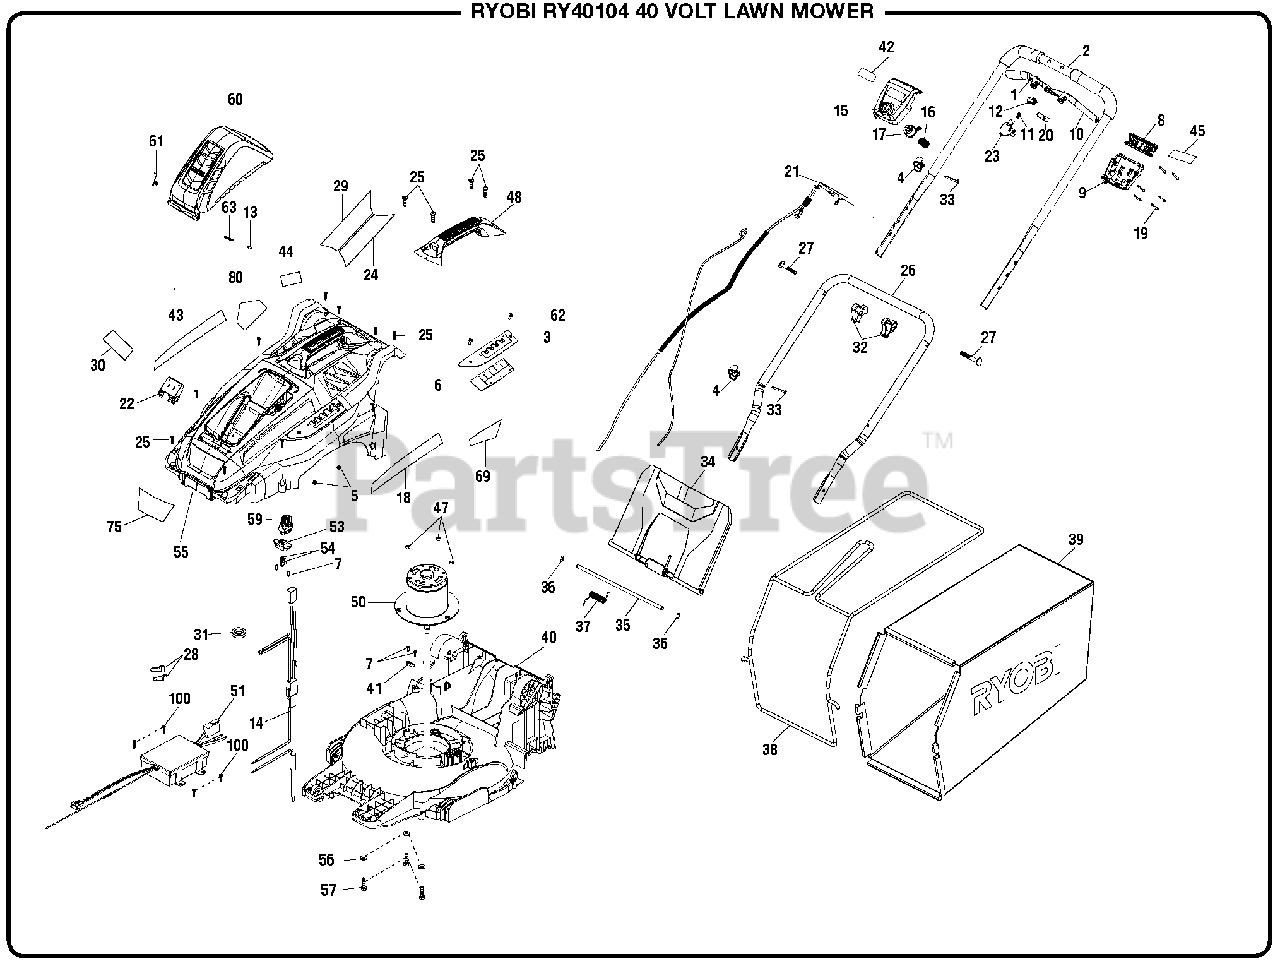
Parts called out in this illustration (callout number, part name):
1	Trigger Handle (Right Power Lever)
2	Upper Handle Assembly
3	Height Adjustment Plate
4	Cord Clamp
5	Lock Nut (M5)
6	Dust Gasket
7	Screw (M4 x 16, T20 Torx Hd.)
8	Lower Cover (Stain Handle)
9	Lower Cover (Trigger Housing)
10	Trigger Handle (Left Power Lever)
11	Compression Spring
13	Battery Door Axle
14	Terminal Block w/Leads
15	Upper Cover (Control Assembly)
16	Compression Spring
17	Start Button
18	Lithium Label (Left)
19	Screw (M4 x 30 mm, T15 Torx Pan Hd.)
21	Starter Cable (Long)
22	Battery Holder Assembly
23	Switch Holder
24	Warning Icon Label (Right)
25	Screw (M3.5 x 20 mm, T20 Torx Pan Hd.)
26	Lower Handle
27	Screw (M8 x 57 mm)
28	Wire Connector
29	Warning Icon Label (Left)
30	Start Key Label (Eng)
31	Ferrite Induct Ring
33	Screw (M3 x 20 mm, Pan Hd.)
34	Rear Discharge Door
35	Rear Door Axle
36	Retaining Ring (E)
37	Torsion Spring (Rear Door)
38	Bag Frame
41	Cord Clamp
42	Ryobi Logo Label (Handle)
43	Lithium Label (Right)
44	Data Label
45	Starting Instructions Label
47	Lock Nut (M6)
51	Soft Start Circuit Board
53	Key Holder
54	Female Terminal
55	Deck Cover
56	Washer (OD15 x ID6 x 1t)
57	Bolt (M6 x 26 mm, Hex Hd.)
59	Start Key
60	Battery Cover
61	Torsion Spring (Battery Door)
62	Screw (M5 x 16 mm, Pan Hd.)
63	Compression Spring
69	Cut Diameter Label (Left)
75	Ryobi Logo Label (Front)
80	Cut Finger Label
100	Screw (M3.5 x 12 mm, T15 Torx Pan Hd.)
